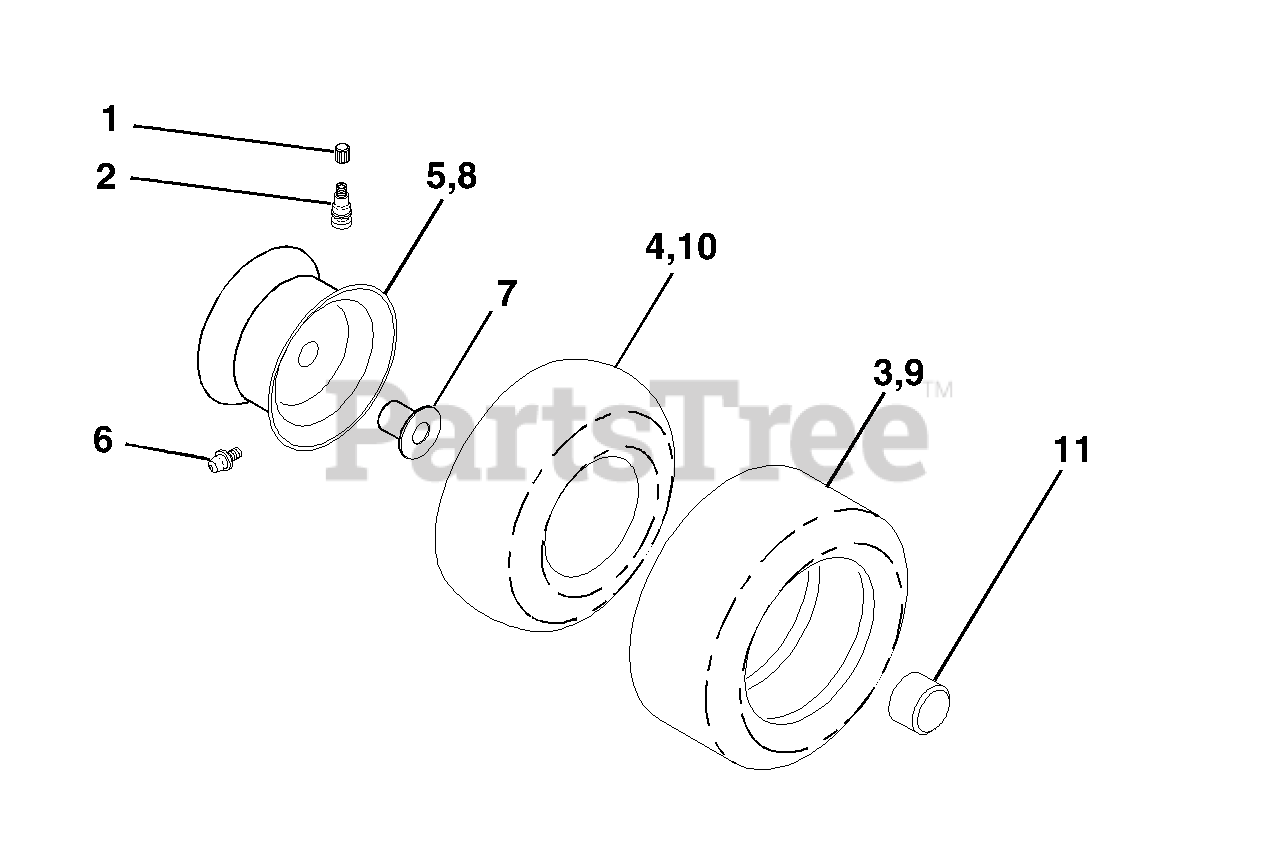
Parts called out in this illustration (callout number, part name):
1	Cap Valve Tire
2	Stem Valve
3	Tire F T 15 X 6 0 - 6 Service
4	Tube Front
5	Rim Asm 6" front Service
6	Fitting Grease
7	Bearing Flange
8	Rim Asm 8" rear Service
9	Tire R T 20x10-8 Service
10	Tube Rear
11	Cap Axle Blk 1 50 X 1 00
